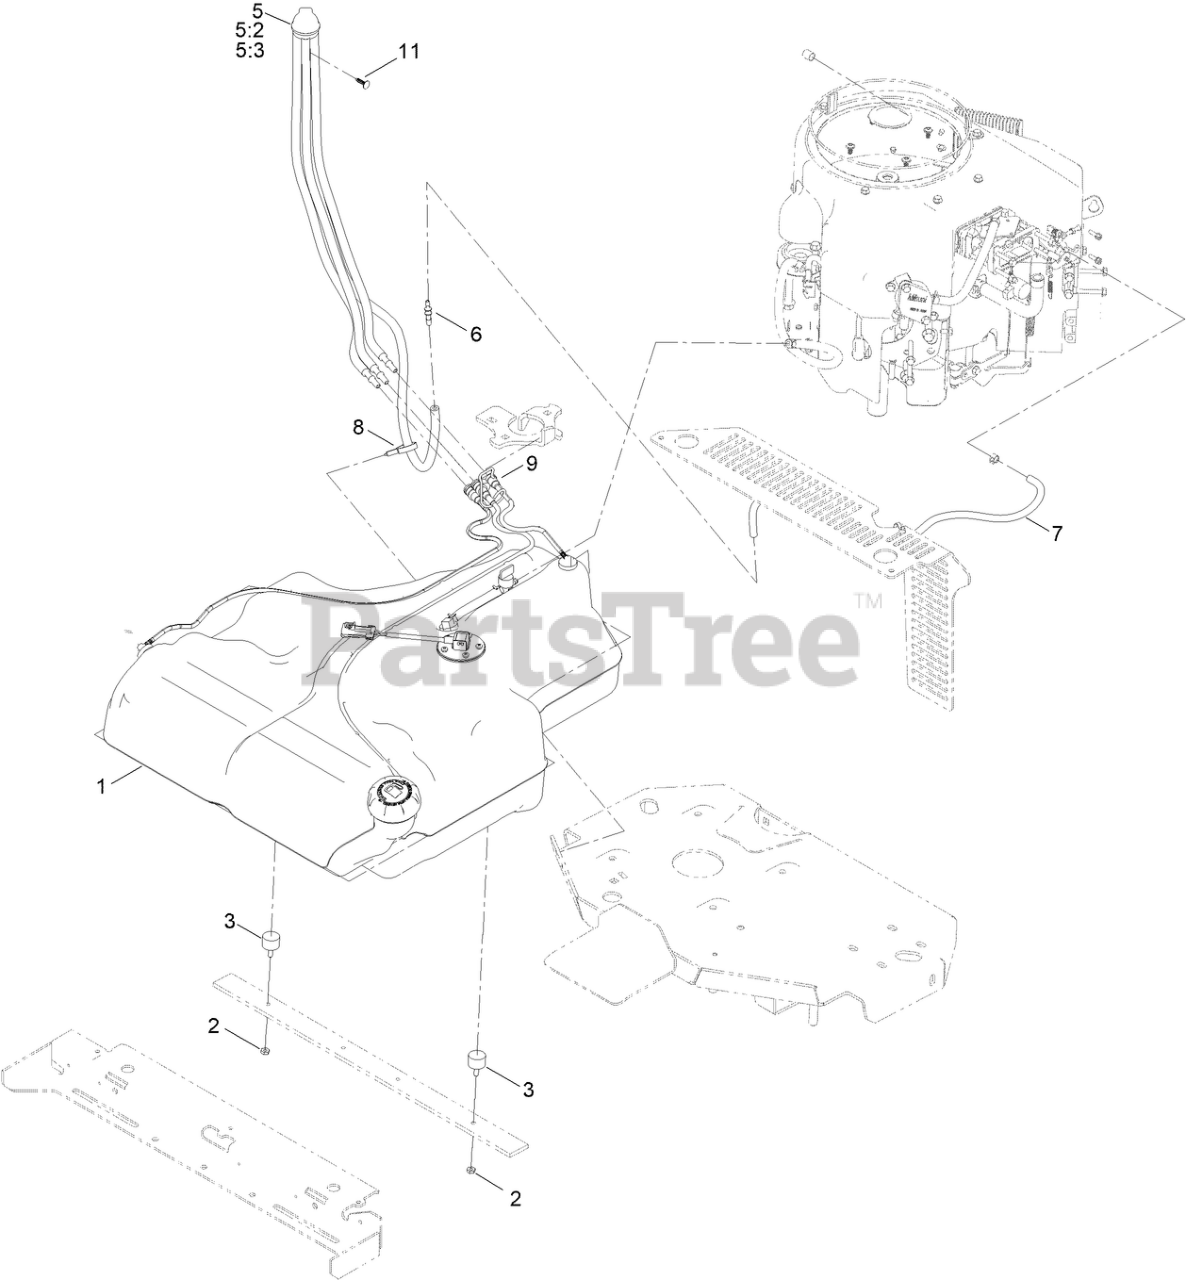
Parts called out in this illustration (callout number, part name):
1	FUEL TANK ASM
2	NUT-JAM
3	BUMPER
5	FUEL MANIFOLD VENT ASM
5:2	HOSE-FUEL
5:3	HOSE-FUEL
6	BARB-FUEL
7	HOSE-FUEL
8	CLAMP-HOSE
9	RETAINER-LINE, VAPOR
11	PLUG-PLASTIC
